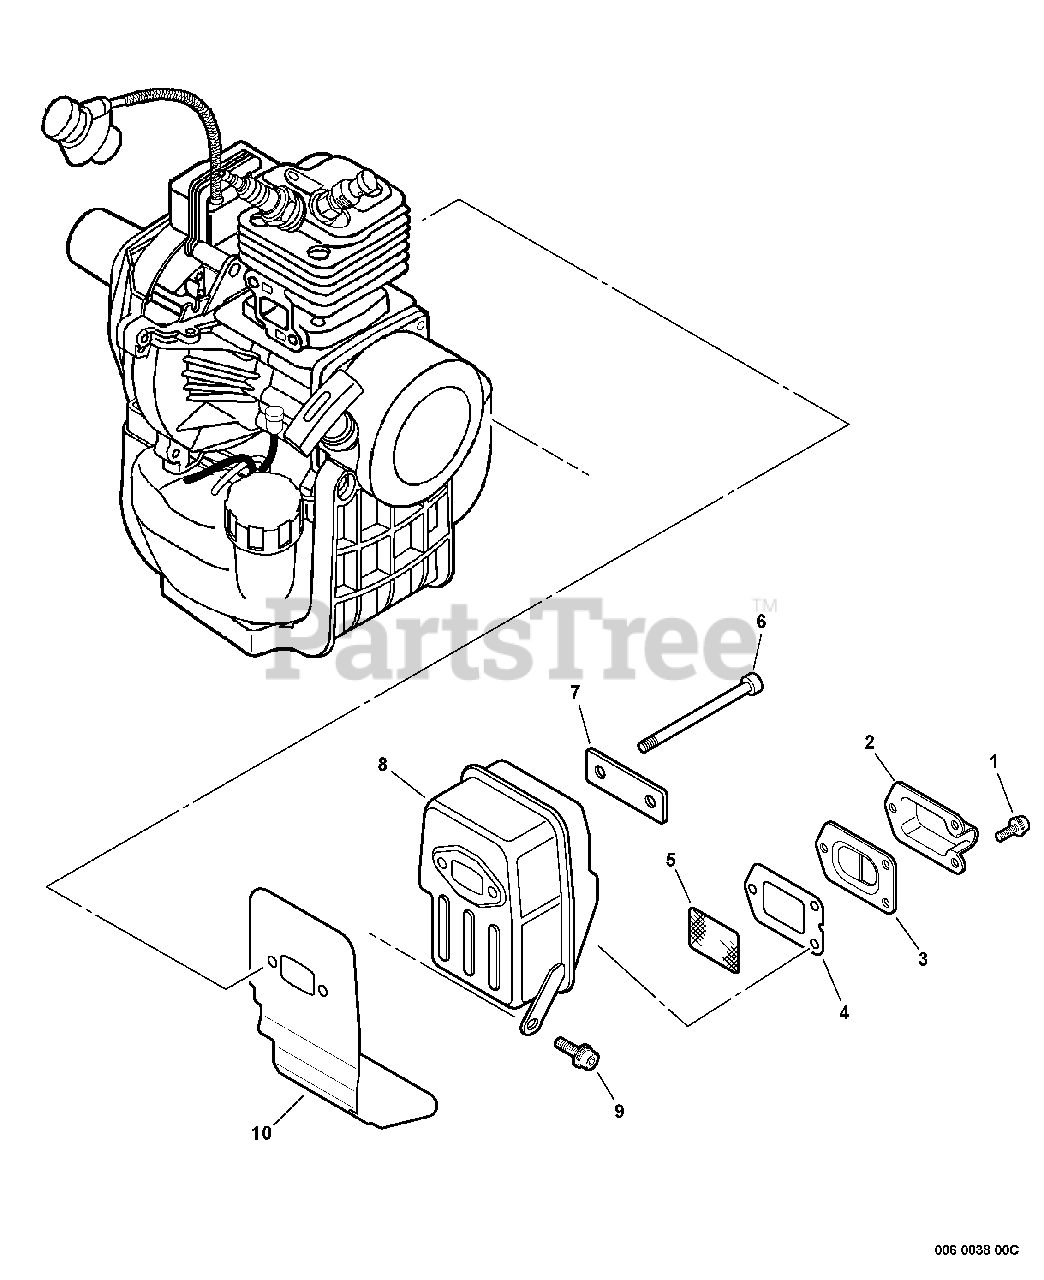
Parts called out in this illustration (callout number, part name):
1	SCREW 4×10
2	OUTLET, EXHAUST
3	GUIDE, EXHAUST
4	GASKET, EXHAUST
5	SCREEN, SPARK ARRESTER
6	BOLT 6×60
7	PLATE, EYE
8	MUFFLER
9	BOLT 5×12
10	HEAT SHIELD, EXHAUST
